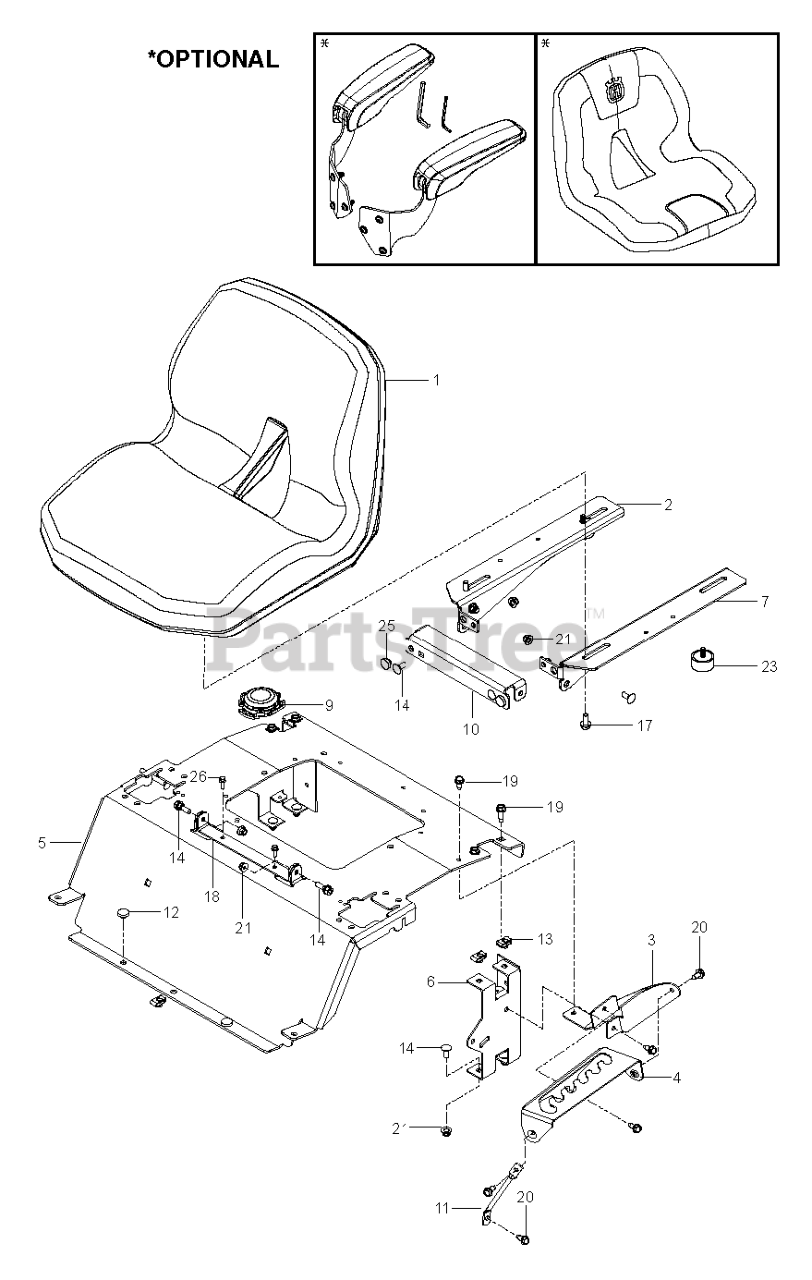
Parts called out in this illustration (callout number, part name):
2	BRACKET SEAT PAN RIGHT BLACK X
3	PLATE.SUPPORT.DECK.LIFT.X431
4	PLATE.DECK.LIFT.X431
5	SUPPORT.SEAT.RZ.HUSQ.ORANGE
6	SUPPORT REAR SEAT BLACK
7	BRACKET SEAT PAN LEFT BLACK X4
9	SWITCH.SEAT.DP W/RAMPS
10	BRACKET FRONT SEAT PAN BLACK X
11	SUPPORT.LEG.DECK.LIFT
12	GROMMET.BUMPER
13	U-CLIP 5/16-18 NUT RETAINER
14	BOLT 5/16C X 3/4" CARRIAGE
17	HHFS 5/16-18 X 3/4
18	BRACKET.SEAT.REINF.X668
19	SCREW.THDROL.5/16-18X3/4.TTY
20	BOLT.5/16HEX.WHS.HD
21	5/16-18 NYLOC FLANGE NUT
23	BUMPER 5/16-18 CLEAR ZINC
25	GROMMET, BUMPER
26	SCREW.FLG.LOCKING.1/4-20X.75
